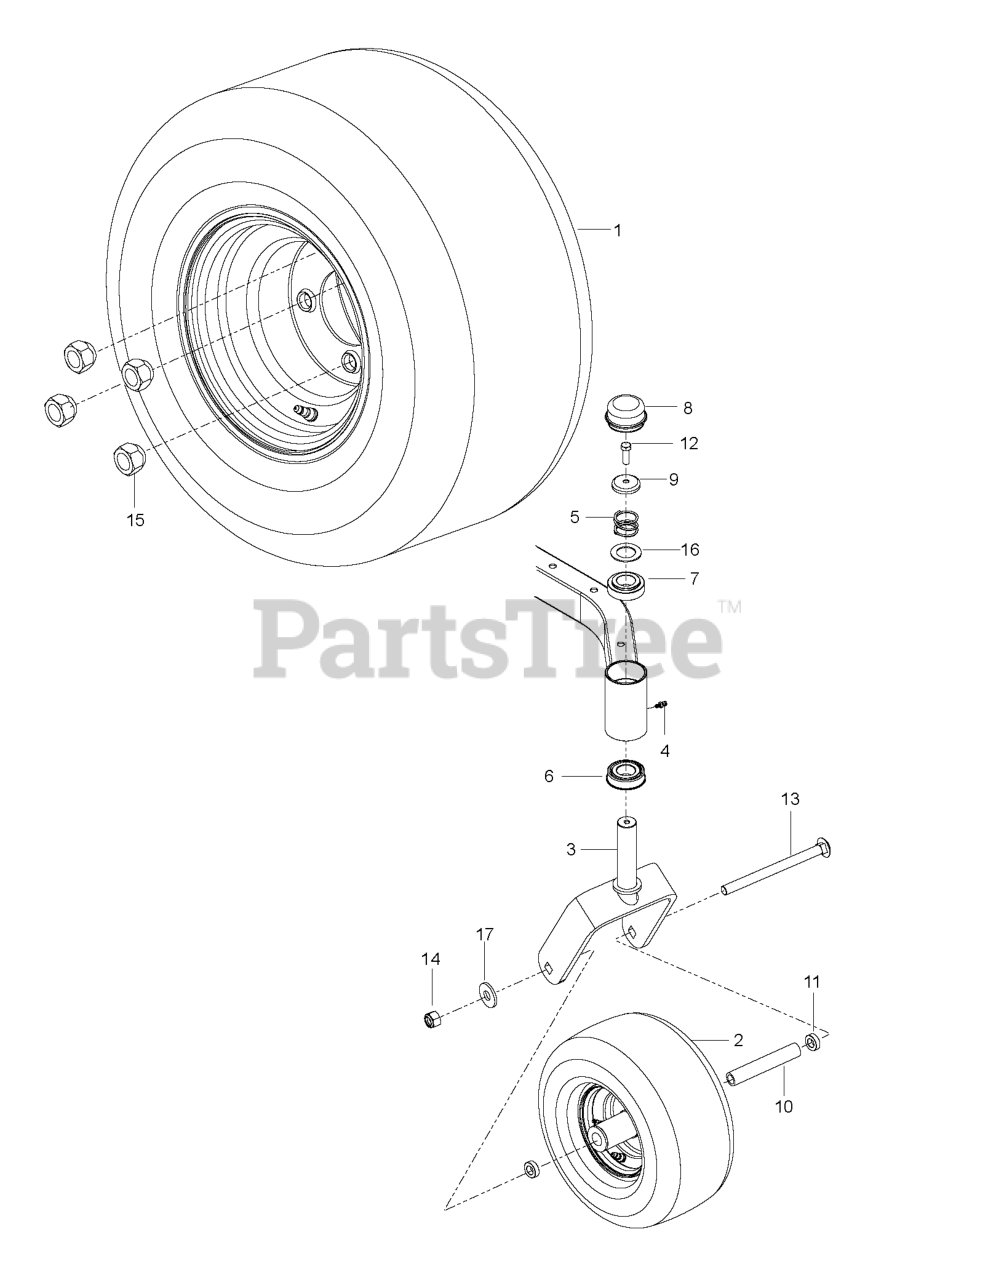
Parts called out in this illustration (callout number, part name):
1	WHEEL.A500.18 X 9.5-8.SILVER
2	WHEEL.11X4-5.K404LG.5X3W/4.188
3	YOKE.CASTER.ORANGE
4	ZERK, 3/16, DRIVE IN
5	SPRING, CASTER
6	BEARING FLANGED
7	BUSHING, CASTER
8	GREASE CAP
9	CASTER.PLUG
10	SPACER, 5/16"
12	5/16-18X1 HHB G5W/NY
13	RHSNB 1/2-13 X 6.50 GR2 ZD
14	NUT 1/2-13 HEX CNTRLK GR 5 ZD
15	LUG NUT 1/2F
16	WASHER, 1.025 ID X 1.64
17	WASHER.9/16 X 1 3/8 X 12 GA.
